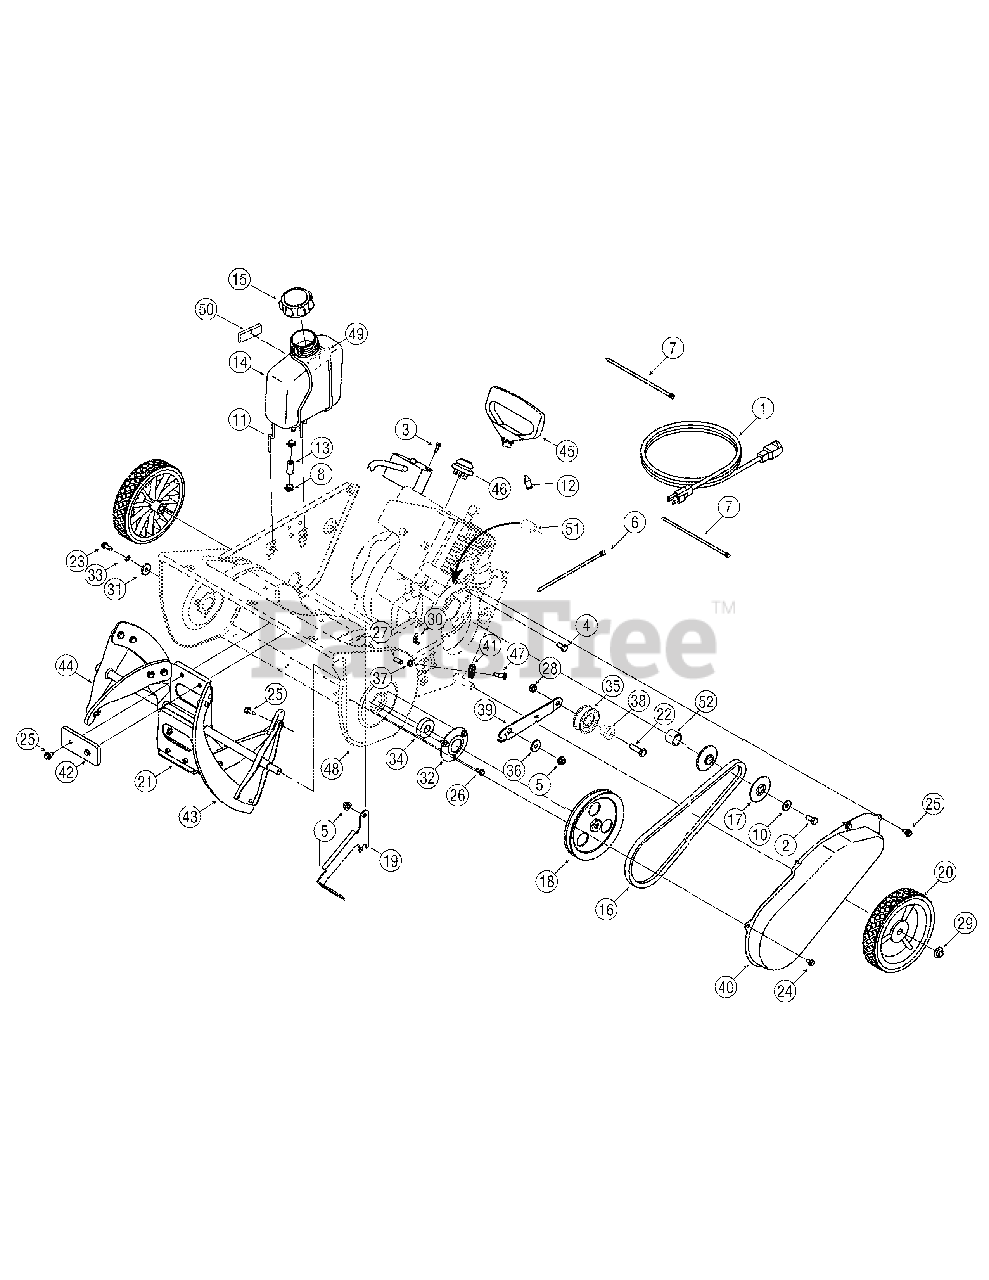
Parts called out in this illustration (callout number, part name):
1	Cord-Extension 110V3M 2 Prong
2	Hex L-Bolt 5/16-24 x .75 Gr. 5
3	Hex Wash B-Tapp Scr #10 x .62" Lg.
4	Screw-Hex Cap
5	Flange Locknut 5/16-18 Gr. F, Nylon
6	Cable Tie
7	Push Mount Tie
8	Hose Clamp
10	Cupped Washer .340 ID x .872 OD x .06
11	Gas Tank Support Wire
12	Choke Lever Knob
13	Fuel Line
14	Fuel Tank 2 Quart
15	Cap-Fuel
16	V-Belt 1/2 x 35.0" Lg.
16	V-Belt (3.5 HP Tec. only)
17	Pulley Half .625 ID x 2.25 OD
18	V-Pulley 1/2 x 6,0" OD ( 5.0 Tec. HP only)
18	Pulley (3.5 HP Tec. only)
21	Auger Assembly
22	Hex Screw 1/4-20 x 1.25 Gr. 5
23	Thd Forming Scr. 1/4-20 x .75 Lg.
24	Hex Wash HD Tapp Scr 1/4-20 x .375
25	Hex B-Tap Scr 1/4-28 x .25" Lg
26	Hex Tap Scr. 1/4-14 x .375" Lg.
27	Hex Bolt 5/16-18 x .75" Lg. Gr. 5
28	Flange Locknut 1/4-20 Gr. F, Nylon
29	Push Cap x 1/2" Rod
30	Extension Spring .33 OD x 1.12 Lg.
31	Flat Washer .25 ID x .93 OD x .125
33	L-Wash 1/4 ID
34	Ball Bearing .625 x 37 x 12.63
35	Idler Pulley (1/4" hole)
36	Shoulder Spacer .25 Thk.
37	Hex Ins Jam L-Nut 1/4-28
38	Shoulder Spacer
41	Cable Guide Roller
42	Rubber Paddle
43	Rubber Spiral-Crescent
44	Auger Ass’y 21" w/Solid Shaft
45	Recoil Handle,Mitten
46	Primer
47	Hex Shld.Scr.1/4-28 x .375
49	Fuel Tank Gasket
50	Tape
51	Spacer .325 ID x .625 OD x .88
52	Spacer .630 x .88 x .747
